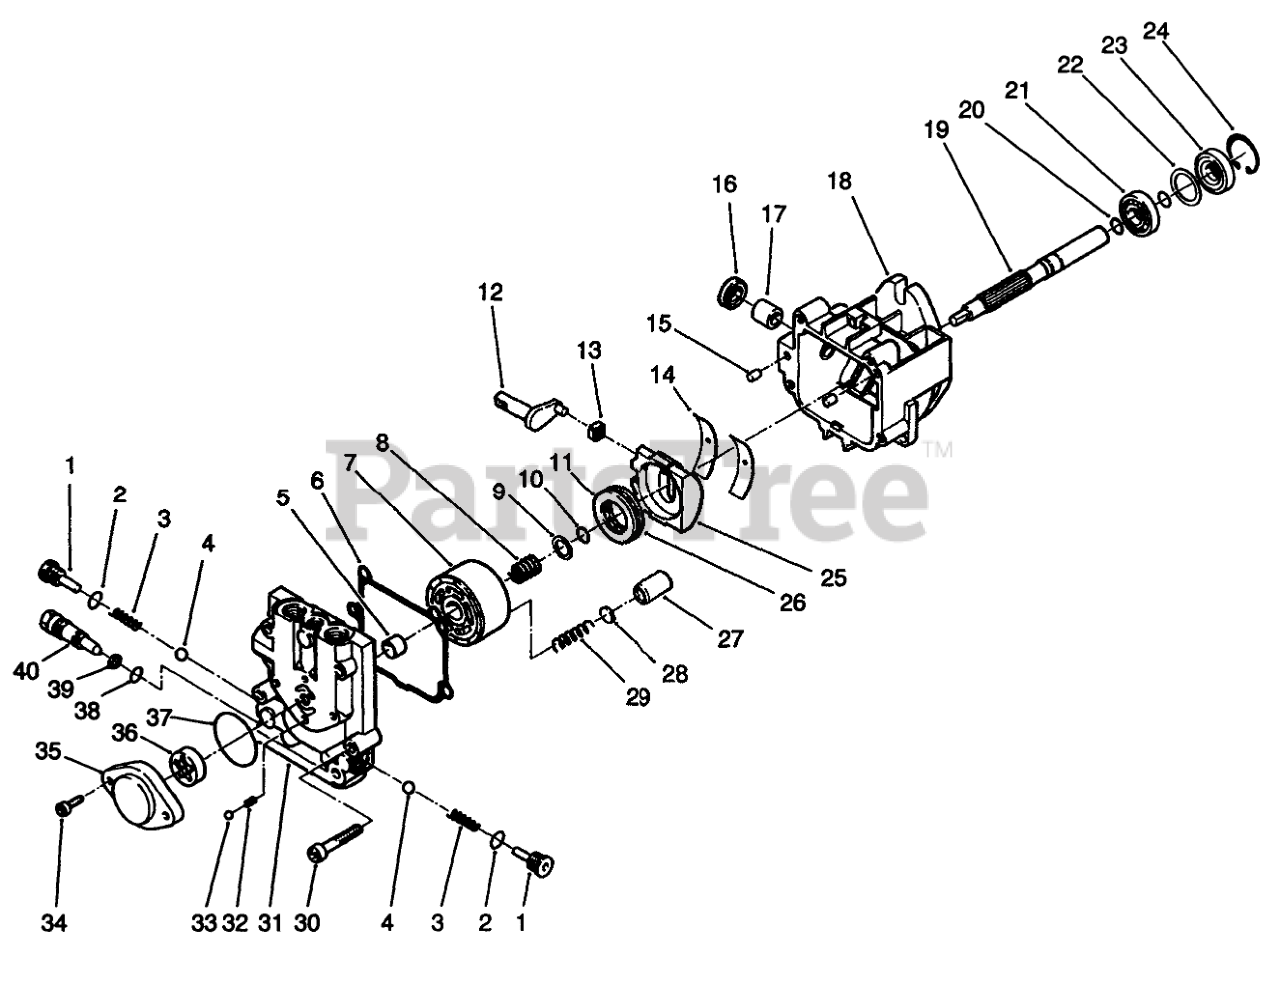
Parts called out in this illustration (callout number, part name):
1	Check Valve Kit (Incl. Ref. #2-4)
2	Seal-O-Ring
4	Ball
5	Journal-Bearing
6	Gasket-End Cap
9	Washer
11	Plate-Thrust
12	Arm-Trunion
13	Guide-Slot
14	Cradle-Bearing
16	Seal-Lip
17	Journal-Bearing
19	Shaft
21	Bearing-Ball
23	Seal-Lip
25	Swashplate Assembly
26	Roller-Thrust
29	Spring-Piston
32	Ball
35	Housing-Charge Pump
36	Gerotor Assembly
37	Seal-O-Ring
38	Seal-O-Ring
39	Ring-Back-Up
40	Valve-Bypass
